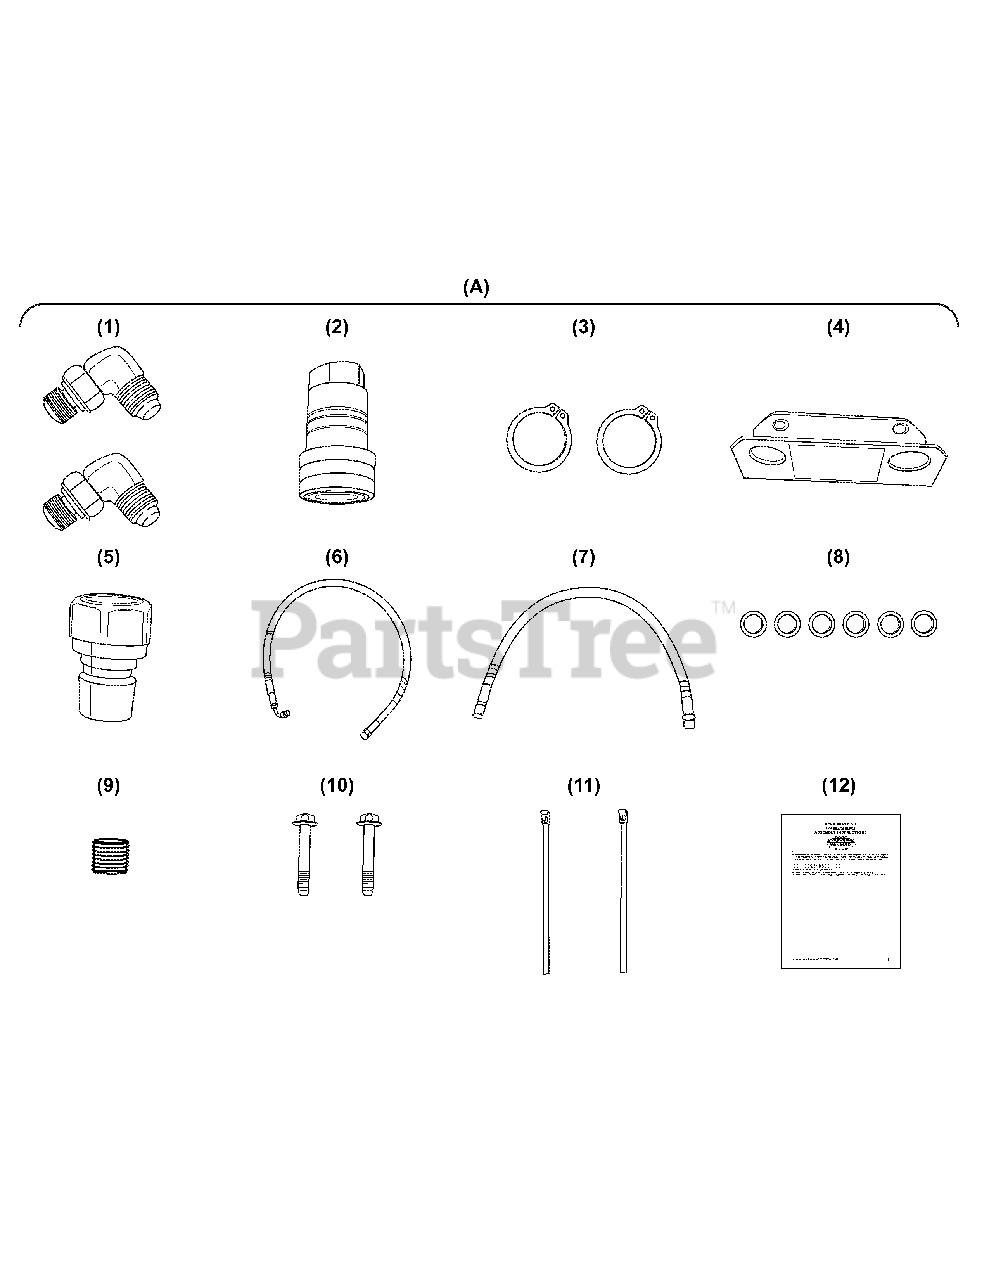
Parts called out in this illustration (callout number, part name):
1	Elbow fittings 90SAE 9/16-18
2	Quick coupler 3/8F
5	Quick coupler 3/8M
8	Gasket 16 × 1.0 (Copper)
10	Bolt M8 × 50 mm (L: 1.97 in.)
12	Assembly Instructions
A	Rear valve kit
